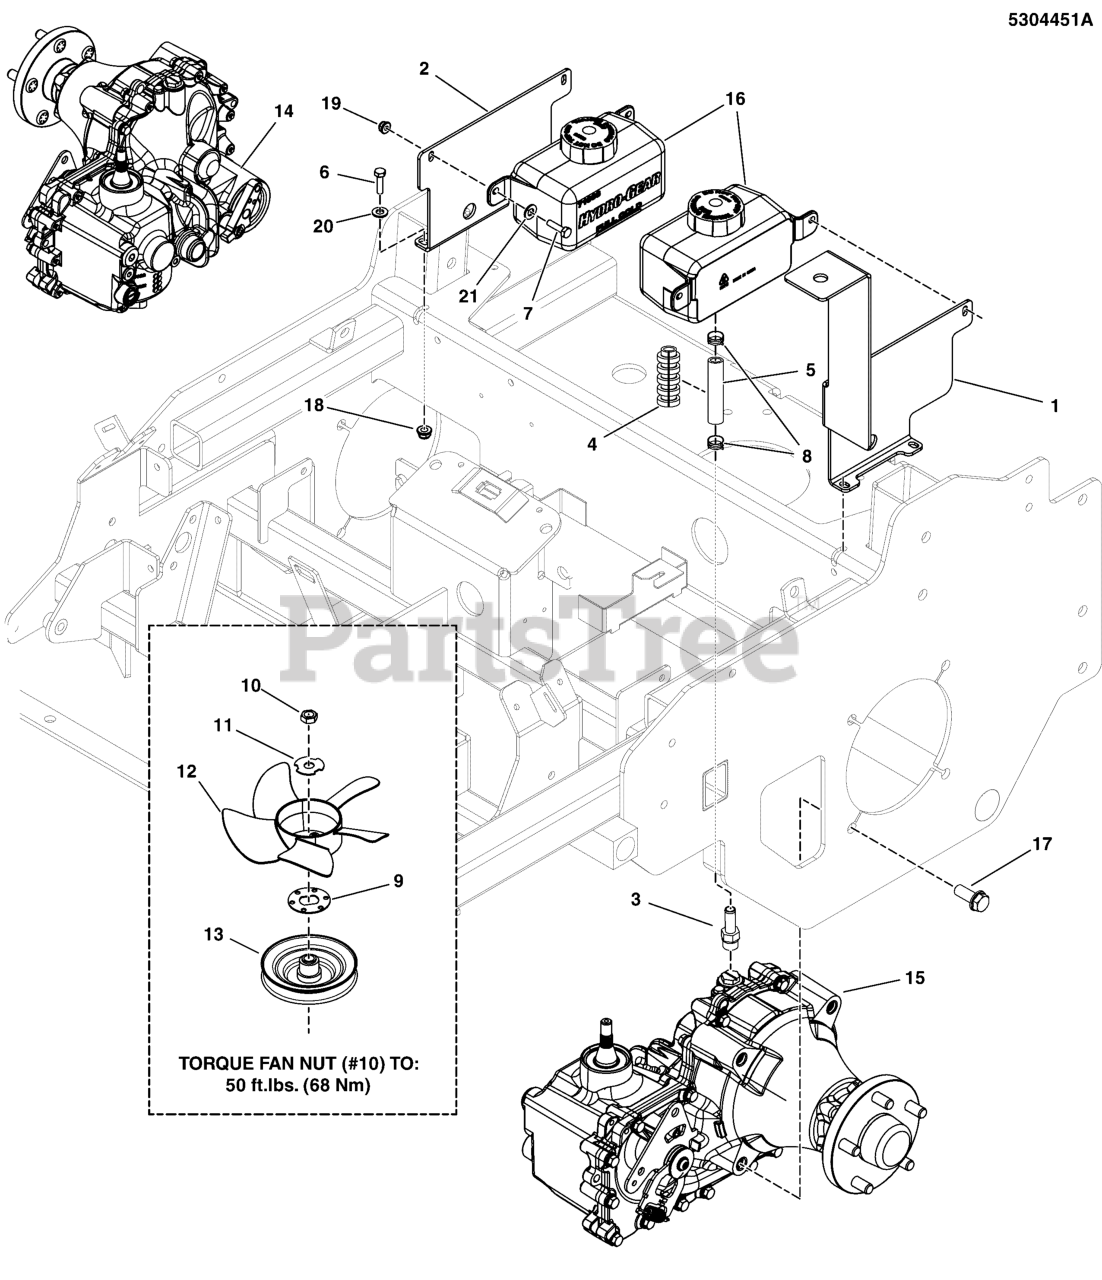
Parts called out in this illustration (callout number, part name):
1	PLATE, HYD BOT FUEL MNT LH, S200XT - BLK
2	PLATE, HYD BOT MOUNT, RH, 200, 320 - RED
3	FITTING, BREATHER, ZT5400
4	LOOM, CONVOLUTED SPLIT, 1 ID - 7.00 LONG
5	HOSE, 5/8 PUSH LOCK, 9.00
6	BOLT, 5/16-18 X 3/4 GD5
7	BOLT, 1/4-20 X 3/4 GD5 CZ
8	CLAMP, #10 HOSE, STAINLESS
9	SPACER, ANTI ROTATE, ZT5400
10	NUT, ZT5400
11	WASHER, ZT5400, SLOTTED
12	FAN, ZT5400
13	PULLEY, ZT5400 (53177)
14	TRANSAXLE, ZT5400, RH, 1015-1057R L AXLE
15	TRANSAXLE, ZT5400, LH, 1015-1057L L AXLE
16	HYDRO TANK, HYDRO-GEAR 71938, 1 LITER
17	BOLT, 1/2-13 X 1-1/4, SF, PLT W/PATCH
18	NUT, 5/16-18 HEX NYLOCK FLANGE
19	NUT, 1/4-20 HEX NYLOCK FLANGE
20	WASHER, 5/16" SAE
21	WASHER, 1/4 SAE
